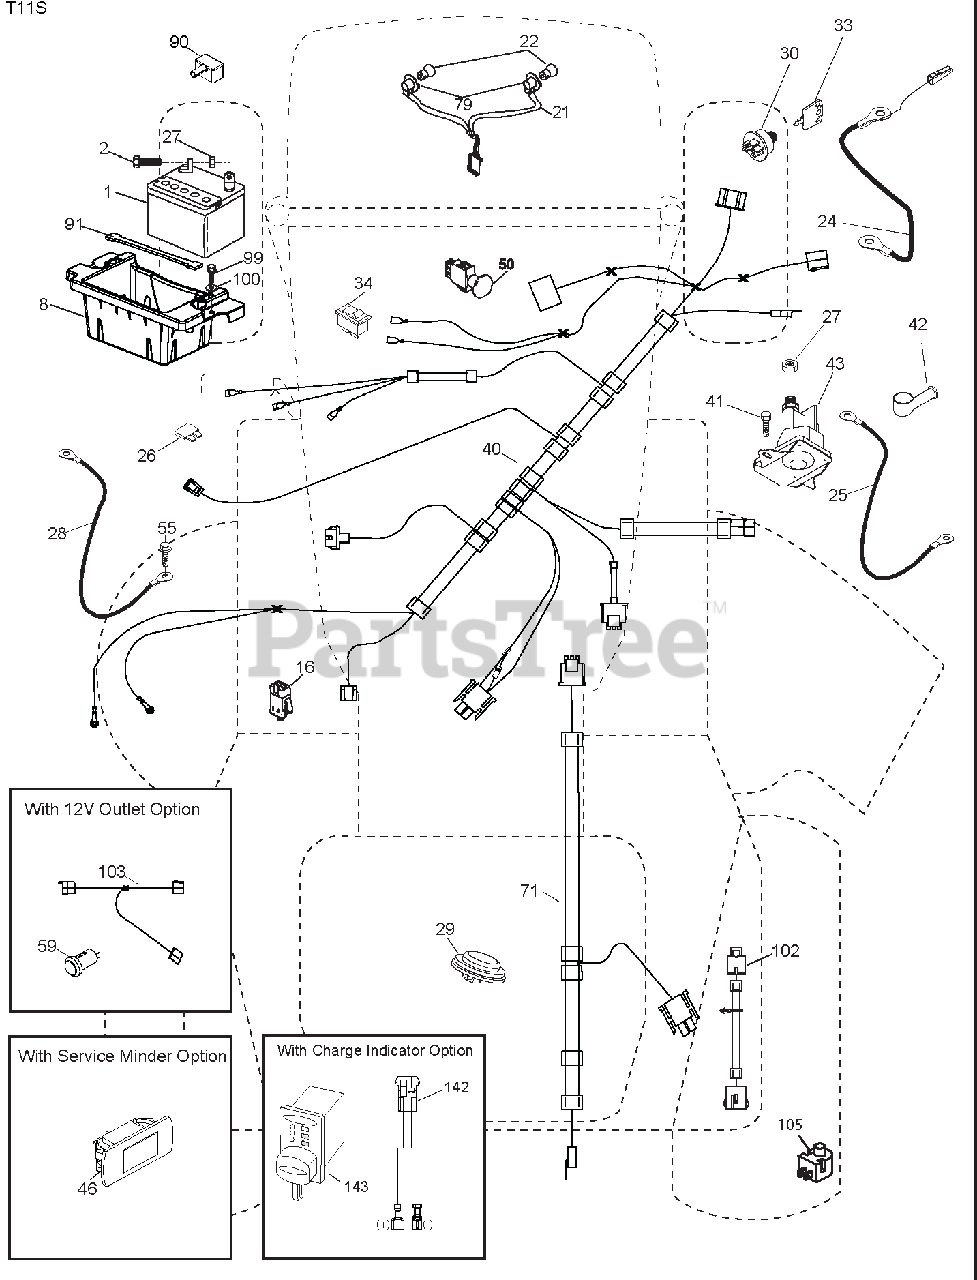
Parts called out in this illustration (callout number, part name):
1	BATTERY.12.VOLT.28.AMP.WET
2	BOLT.HEX.HD.1/4-20UNC X 3/4
8	BOX.BATTERY.MOUNT.FRONT.LT
16	SWITCH.INTERLOCK.NONO.GRAY
21	HARNESS ASM.LIGHT.22"(4152J)
22	BULB.LIGHT.#1156
24	CABLE.BTRY.PSWRE.DSH SOL.8"TEX
25	CABLE.STARTER
26	FUSE.20 AMP.
27	Nut, Keps Hex 1/4-20 unc
28	CABLE.GROUND.21"BLK.6 GA.90T
29	SWITCH.SEAT.DELTA.OPC.9LB.
30	SWITCH.IGN.DLTA.P-IN.ROS
33	KEY/CHAIN.BLISTER PACK.GEN.USA
34	SWITCH.LIGHT/RESET.B/B/RED.
40	HARNESS.IGN.DASH.HUSQ/PRED.
41	Screw 1/4-20 x 1/2
42	COVER.TERMINAL.RED
43	SOLENOID.W/BRASS PLUNGER.2005
46	HOUR METER
50	SWITCH.PTO.8 TERMINAL.BLACK
55	SCREW.5/16-18X3/4.SMGML.TAP/R
71	HARNESS.IGN.CHASSIS.TEX
79	SOCKET ASM.BULB.TWISTLOCK
90	COVER TERMINAL BATTERY FR. TEX
91	STRAP.BATTERY.MOUNT.FRONT
99	SCREW.HEXWSH.THDROL.1/4-20X3/4
100	WASHER.9/32 X 7/8 X 16GA.
102	HARNESS.PIGTAIL.K46.TEX.ROS
105	SWITCH.REVERSE.TT.PEDAL CONTRO
